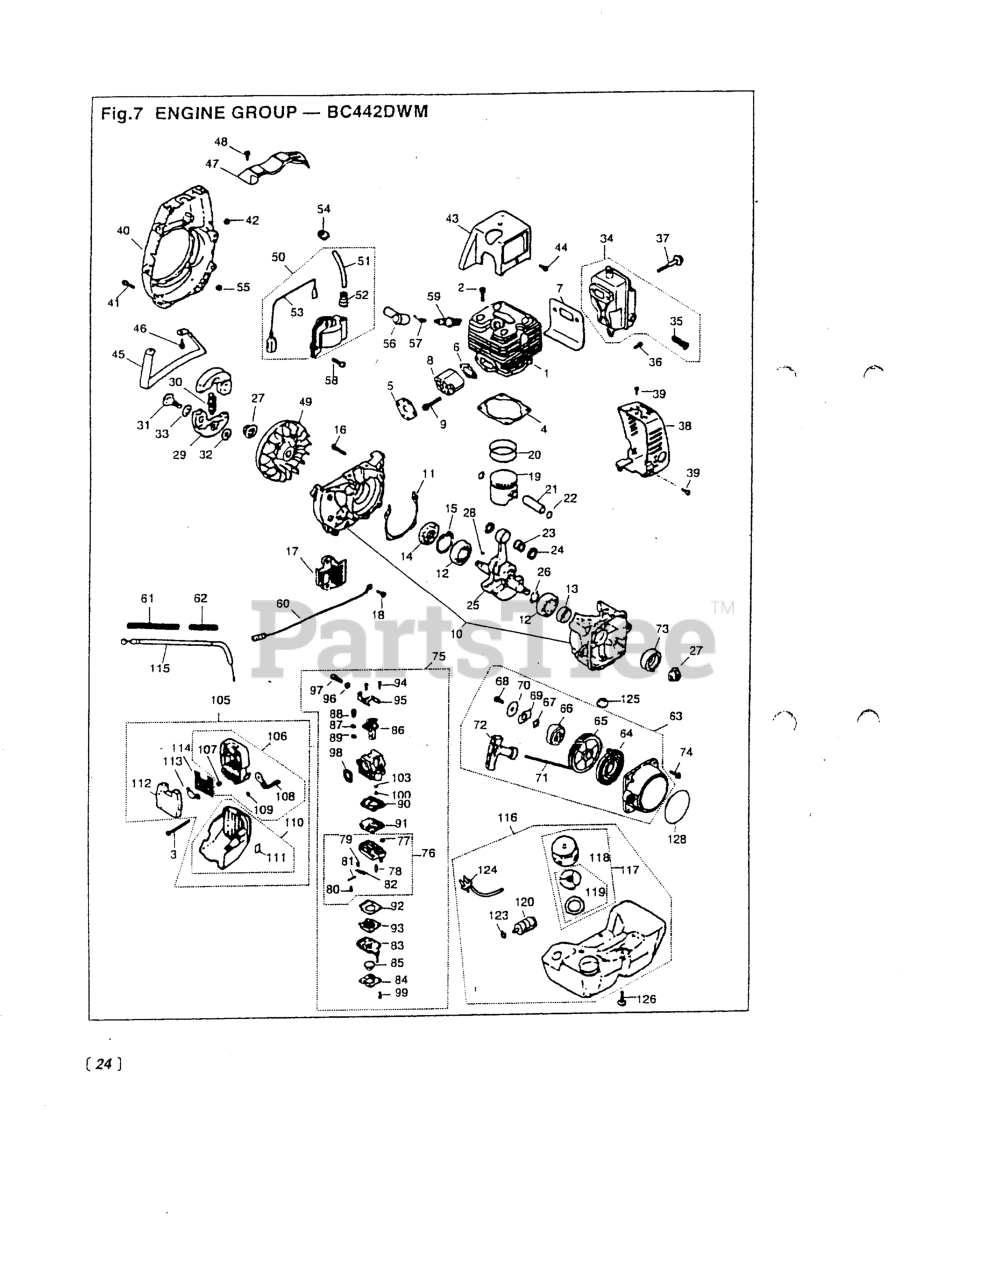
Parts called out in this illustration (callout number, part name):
1	CYLINDER (RPLS -12112)
2	BOLT M5 x 20 (RPLS -12280)
8	INSULATOR (RPLS -13162)
9	SCREW, M5 X 40
10	CRANKCASE COMPLETE
13	SEAL, OIL - STARTER SIDE
15	RING, SNAP, M35 X 1.5
16	BOLT, M5 X 30
17	GUARD (RPLS-21310)
18	SCREW,M5 X 14 (RPLS 1400-15510
19	PISTON
20	RING
21	PIN, PISTON
22	RING, SNAP
23	BEARING
24	WASHER (RPLS 1491-41510)
25	SHAFT (RPLS -42001)
26	SHIM (REPLACES 848-870-G000)
27	NUT, M10
28	KEY
31	SCREW
32	WASHER
33	WASHER (USE -51241)
35	ARRESTER
36	SCREW, M5 X 12
37	BOLT
38	COVER
39	SCREW, M5 X 12
40	COVER, FAN (REPLACES -31111)
41	BOLT M5 x 20 (RPLS -12280)
43	COVER (RPLS -32110)
44	SCREW, M5 X 12
45	STAND
46	BOLT (REPLACES 01252-30514)
48	SCREW, M5X20 (RPLS.1400-75510)
50	COIL ASSEMBLY
52	CAP
54	GROMMET
57	SPRING
58	SCREW, M5X20 (RPLS.1400-75510)
62	TUBE (RPLS -72930)
64	SPRING (RPLS -75220)
66	DOG
67	WASHER
68	SCREW
69	RETAINER (RPLS 1861-75161)
70	WASHER
71	ROPE
72	KNOB
73	PULLEY (RPLS -75210)
74	SCREW, M5X20 (RPLS.1400-75510)
75	CARBURETOR ASSEMBLY
76	BODY, PUMP
78	VALVE, INLET
79	SPRING, METERING LEVER
80	SCREW, METERING LEVER PIN
81	PIN, METERING LEVER
82	LEVER
83	BODY, PURGE
84	COVER, PUMP
85	PUMP, PRIMING
86	VALVE ASSY
87	WASHER
88	SWIVEL
89	RING
90	GASKET, PUMP
91	DIAPHRAGM
92	GASKET, DIAPHRAGM
93	DIAPHRAGM (USE 4810-81260)
94	SCREW
96	NUT, CABLE ADJUSTER
98	RING, PACKING
99	SCREW
103	RING, O
107	SLEEVE
110	COVER, AIR FILTER (RPLS -82201
111	LABEL
113	PLATE
115	CABLE COMPLETE
118	VALVE COMPLETE
119	PACKING (RPLS -85321)
120	FILTER ASSY
123	CLIP (REPLACES 2841-31280)
124	PIPE ASSY (RPLS -85800)
126	SCREW
128	LABEL, RECOIL(RPLS 1403-75411)
